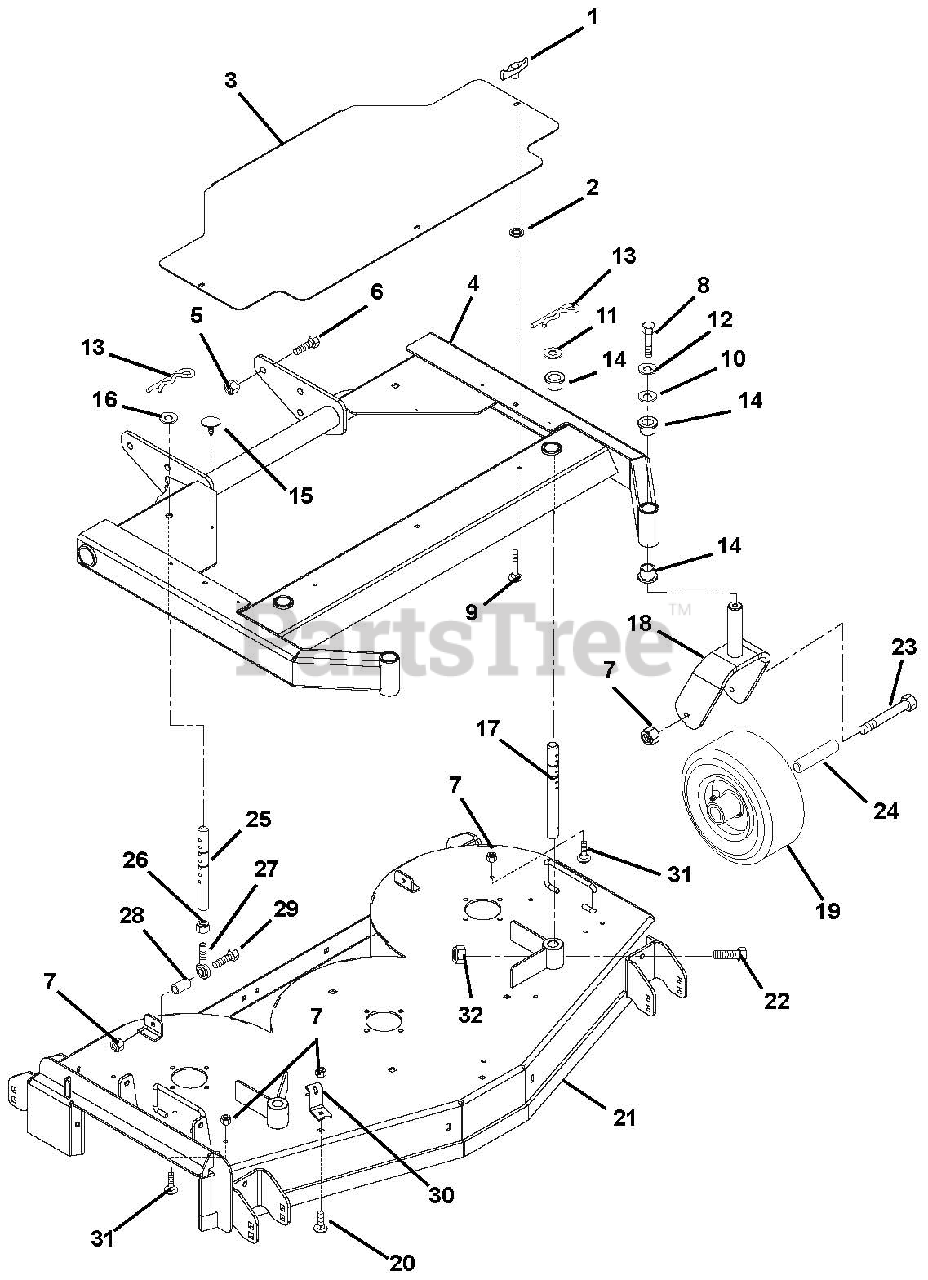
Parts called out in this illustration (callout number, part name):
1	Knob- Wing .312-18
2	Nut-Push .312
3	Cover, Belt Pro Mower
4	Weldment-Mower Frame 48" Floating
5	Nut-Locking-Nylon .625-11
6	Bolt-Hex .62-11 x 1.50
7	Nut-Locking-Top-Flange .38-16
8	Bolt-Hex .38-16 x 1.25 Grade 5
9	Bolt-Round Head Square Neck .31-18 x 1.00
10	Washer-Flat-Steel .38 x 1.50 x .125
11	Washer-Flat-Steel .875 x 1.50 x .120
12	Washer-Locking .38 x .094 Regular
13	Pin-Hair-Internal .17 x .68 x 3.50
14	Bushing-Flange 1.00 x 1.25 x 1.50 x 1.50
15	Bumper Grommet .125 x .25 Dia.
16	Washer-Flat-Steel .688 x 1.75 x .134
17	Rod- Front Height Adjustment
18	Weldment-Caster Fork
19	Wheel 9 x 3.50
20	Bolt-Round Head Square Neck .38-16 x 1.00 Grade 5
21	Kit, 48" Floating Mower Deck with Decals
22	Bolt-Hex .25-20 x 2.25 Grade 8
23	Bolt-Hex .38-16 x 5.50
24	Bearing .625 x .380 x 4.08
25	Rod- Rear Height Adjustment
26	Nut-Jam .375-24
27	Rod End, .38 Right Hand
28	Bushing-Sleeve .377 x .624 x .37
29	Bolt-Hex .38-16 x 1.50 Grade 5
30	Anchor, Spring
31	Bolt-Round Head Square Neck .38-16 x .75 Grade 5
32	Nut-Locking-Top-Flange .25-20
